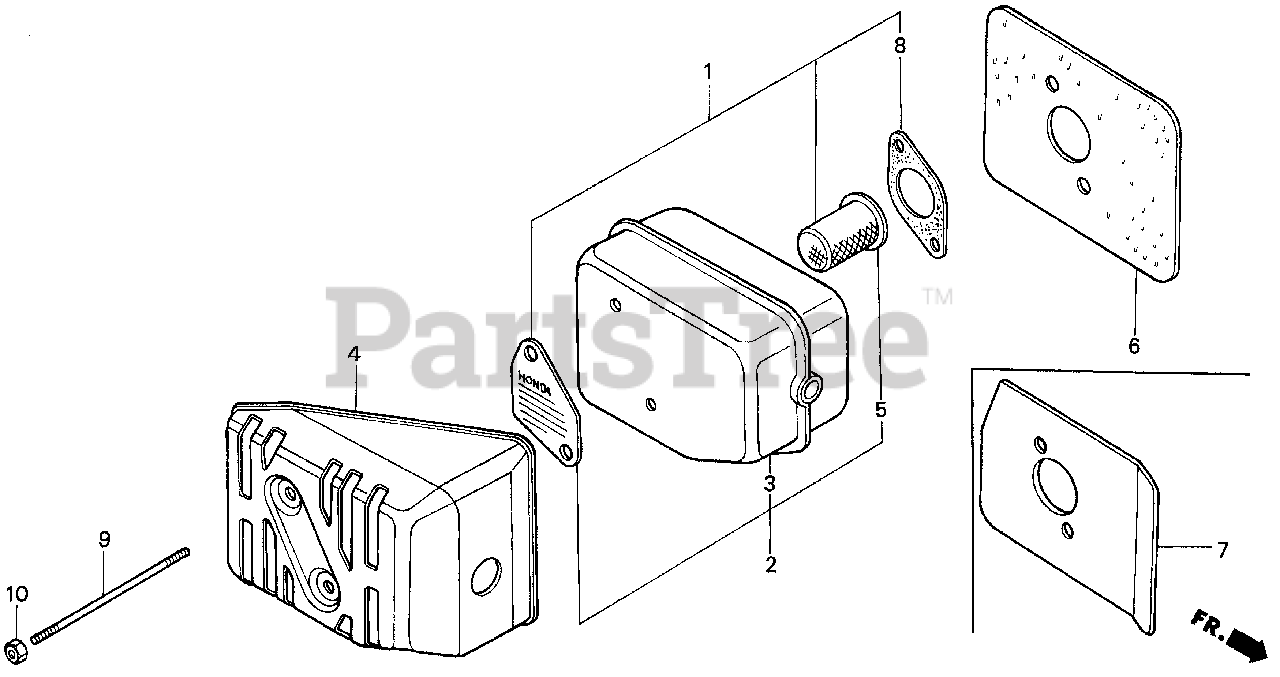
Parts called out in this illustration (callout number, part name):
1	ARRESTER KIT, SPARK
3	MUFFLER
4	PROTECTOR, MUFFLER
5	ARRESTER KIT, SPARK
7	GASKET, MUFFLER
8	GASKET, MUFFLER
9	BOLT, STUD (6X85)
10	NUT, SELF-LOCK (6MM)
